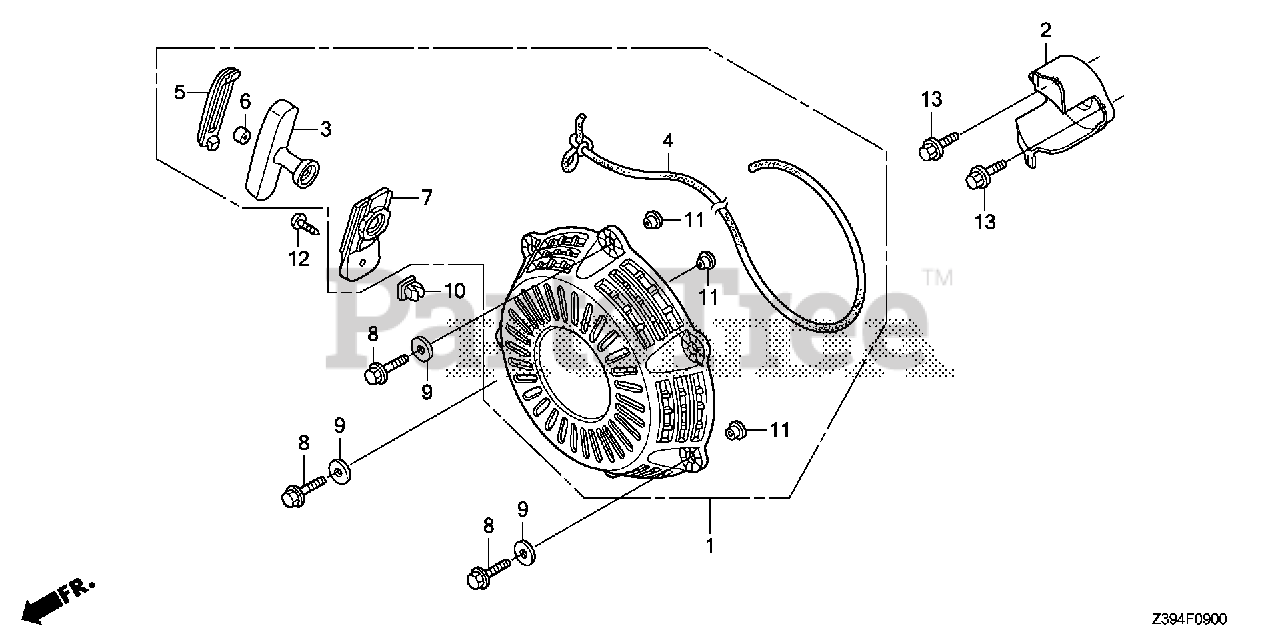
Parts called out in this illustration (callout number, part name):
1	STARTER ASSY., RECOIL
1	STARTER ASSY., RECOIL (COO)(FOR U.S.A.)
2	PULLEY, STARTER
3	GRIP, STARTER
4	ROPE, STARTER
5	COVER, GRIP
6	REINFORCEMENT, GRIP
7	GUIDE, STARTER ROPE
8	BOLT, FLANGE (6X20) (CT200)
9	WASHER, PLAIN (6.5X15)
10	GROMMET, SCREW (6MM)
11	COLLAR, RECOIL STARTER
12	SCREW, TAPPING (5X16) (PO)
13	BOLT, FLANGE (6X12)
